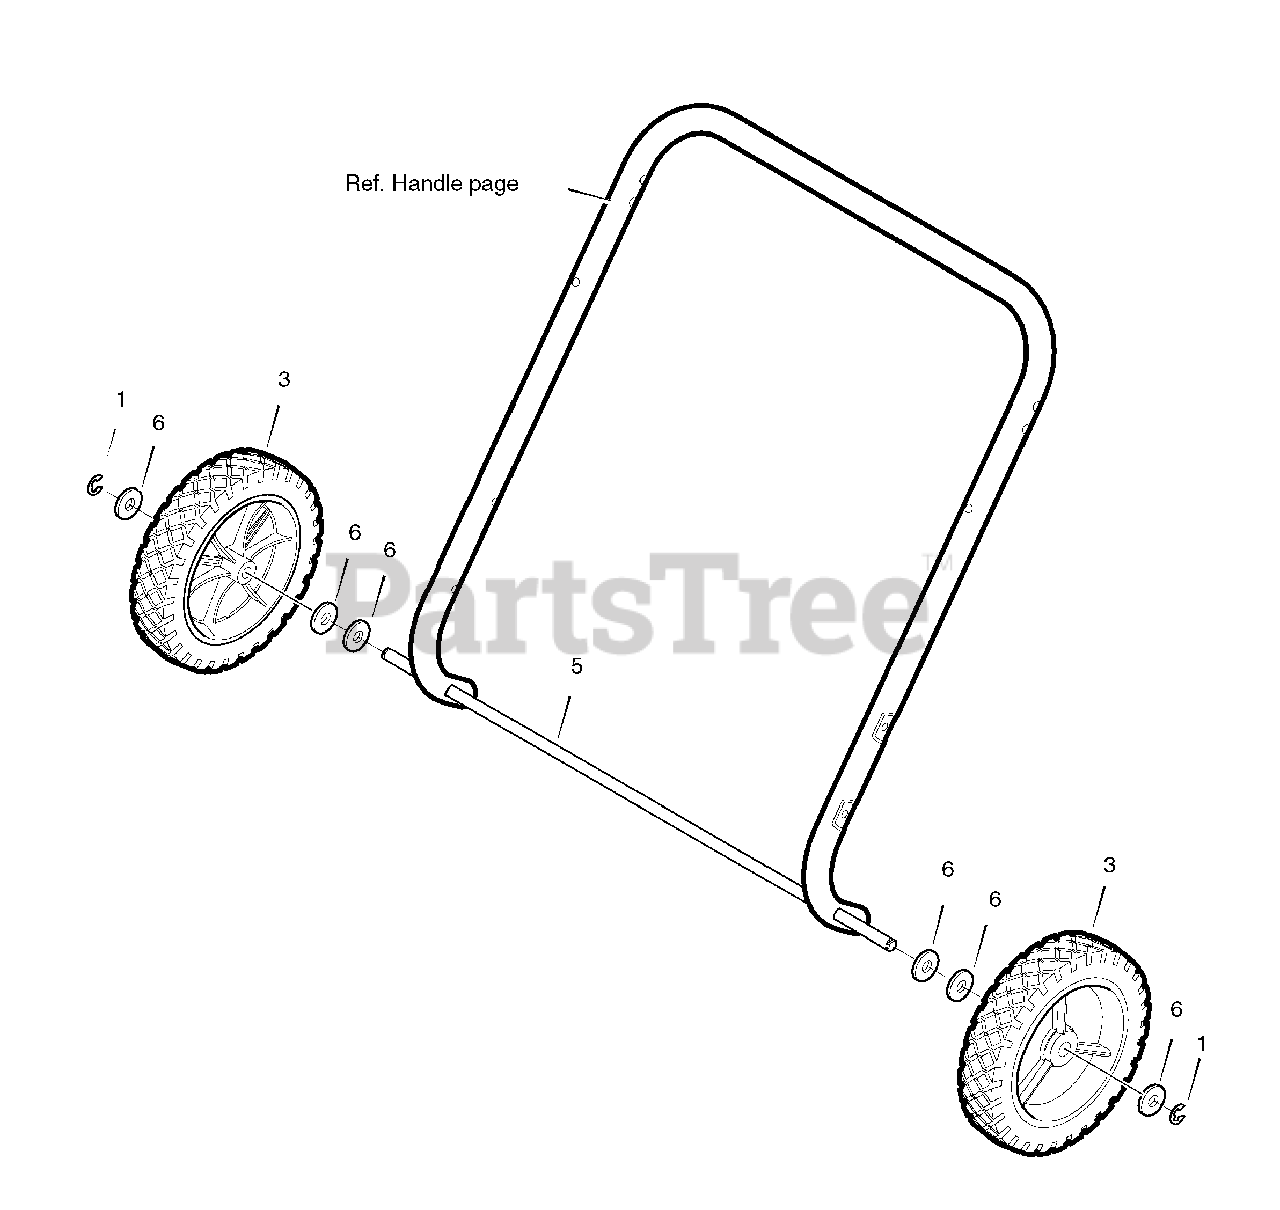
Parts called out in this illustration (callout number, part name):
1	RETAINER, E-Ring
3	WHEEL & TIRE, 7" x 1-1/2"
5	ROD, Axle
6	WASHER
